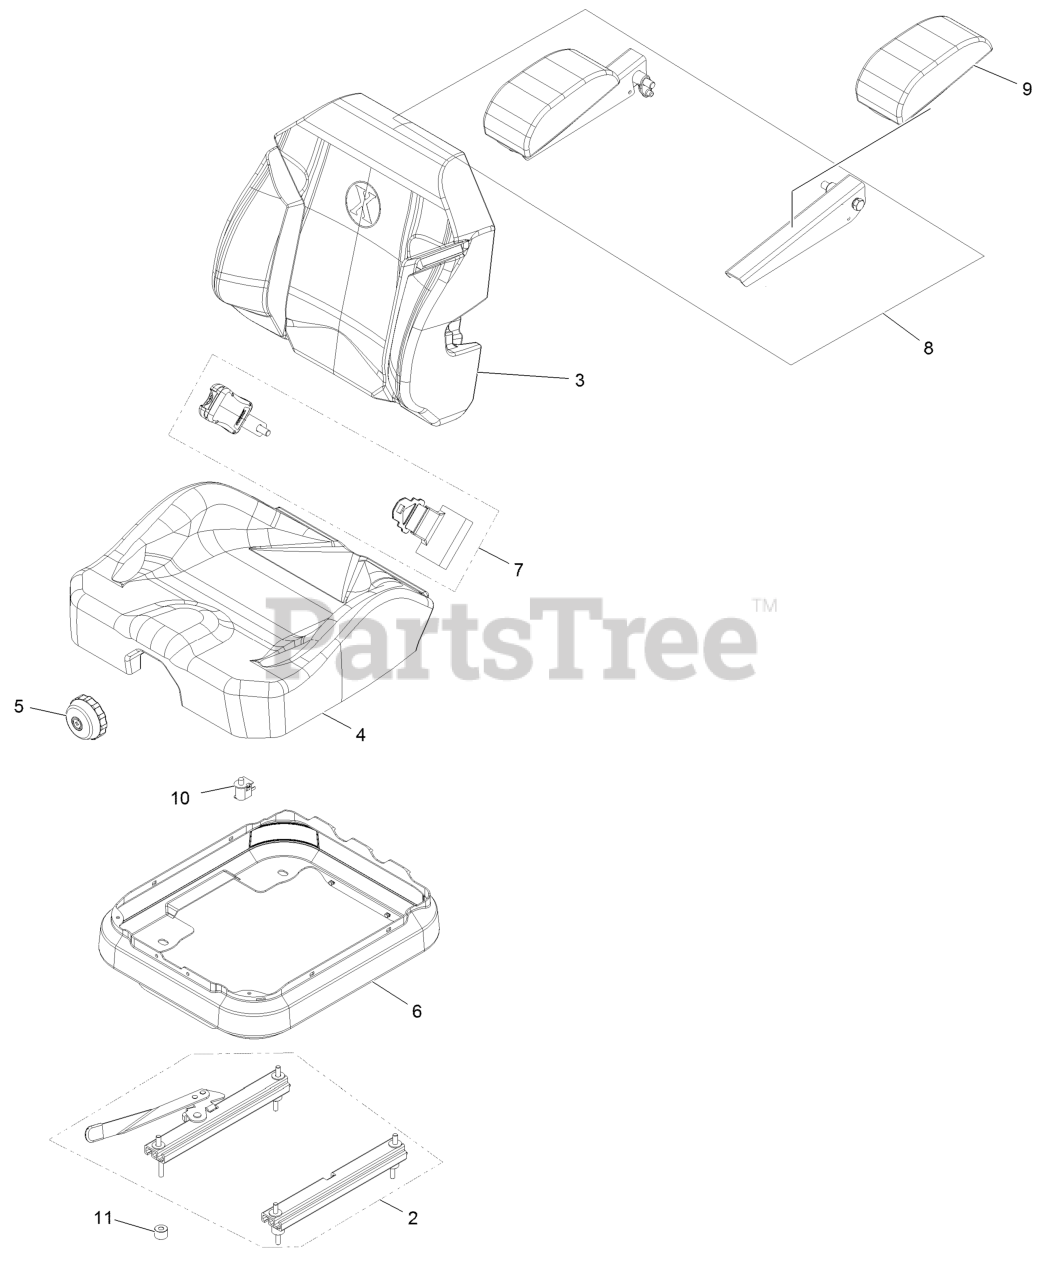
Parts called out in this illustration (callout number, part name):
2	NUT-JAM
4	HOSE ASM
5	FUEL MANIFOLD VENT ASM
6	FITTING-STRAIGHT
7	HOSE-FUEL
8	CLAMP-HOSE
9	RETAINER-LINE, VAPOR
